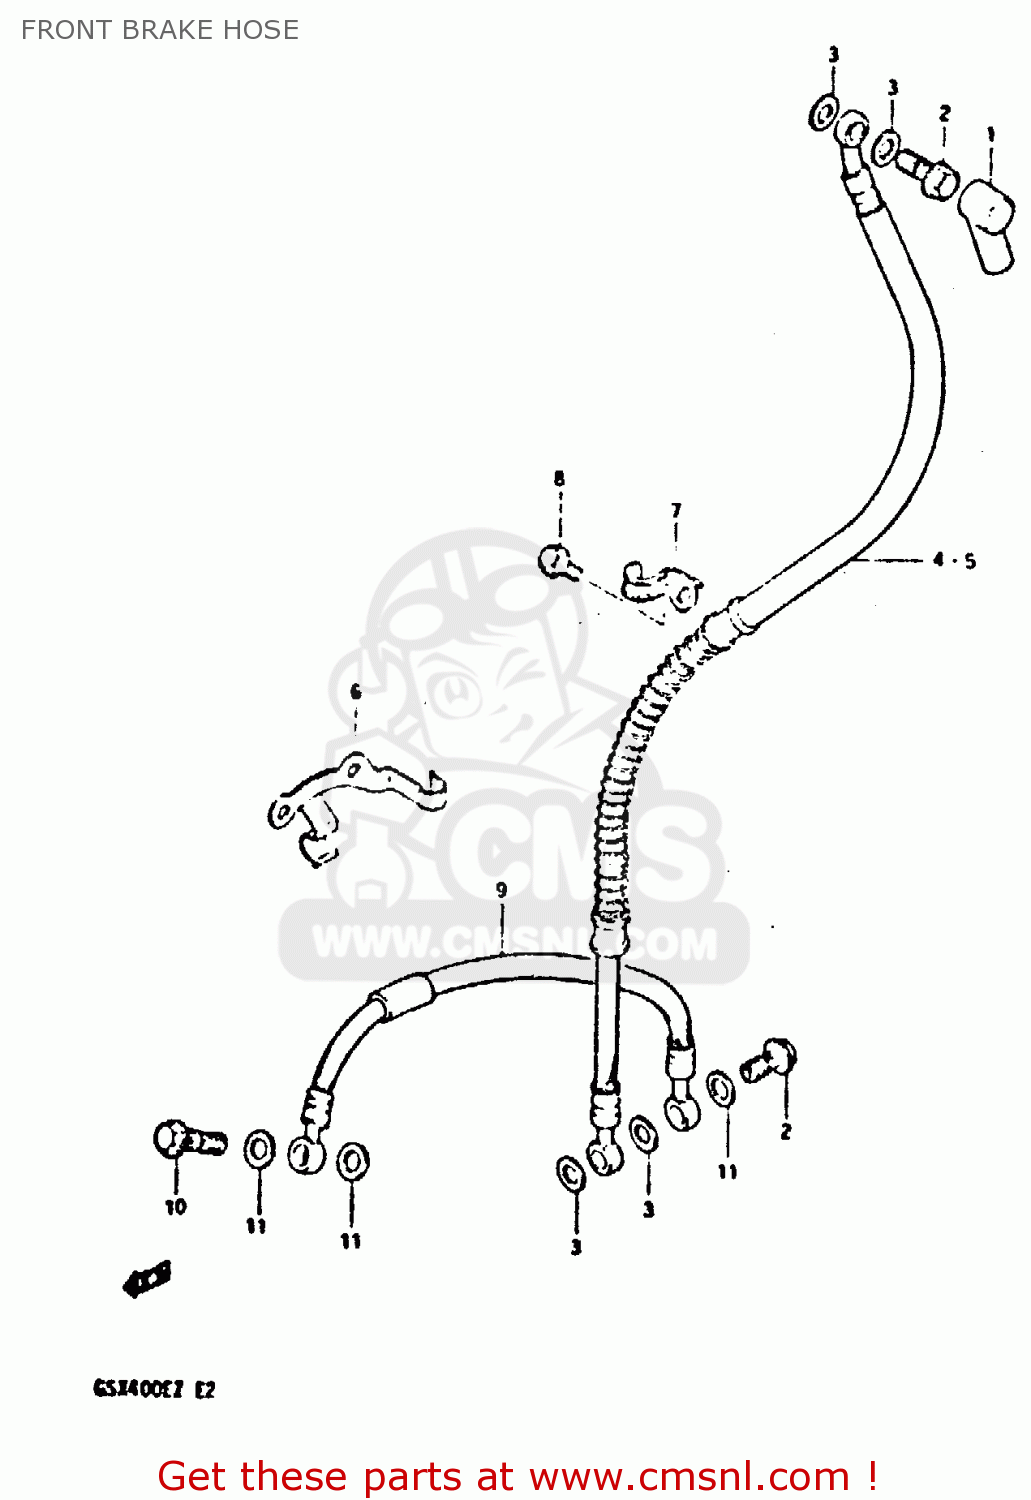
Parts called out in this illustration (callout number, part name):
1	BOOT,MASTER CYLINDER
2	BOLT,UNION
3	WASHER
4	HOSE, BRAKE NO.1 (NEUTRAL TYPE)
5	HOSE, BRAKE NO.1 (FLAT TYPE)
6	GUIDE,BRAKE HOSE NO.3
7	BOLT
8	HOSE,ANTI NOSE
9	BOLT,UNION
10	WASHER
11	CLAMP,FRONT BRAKE HOSE
